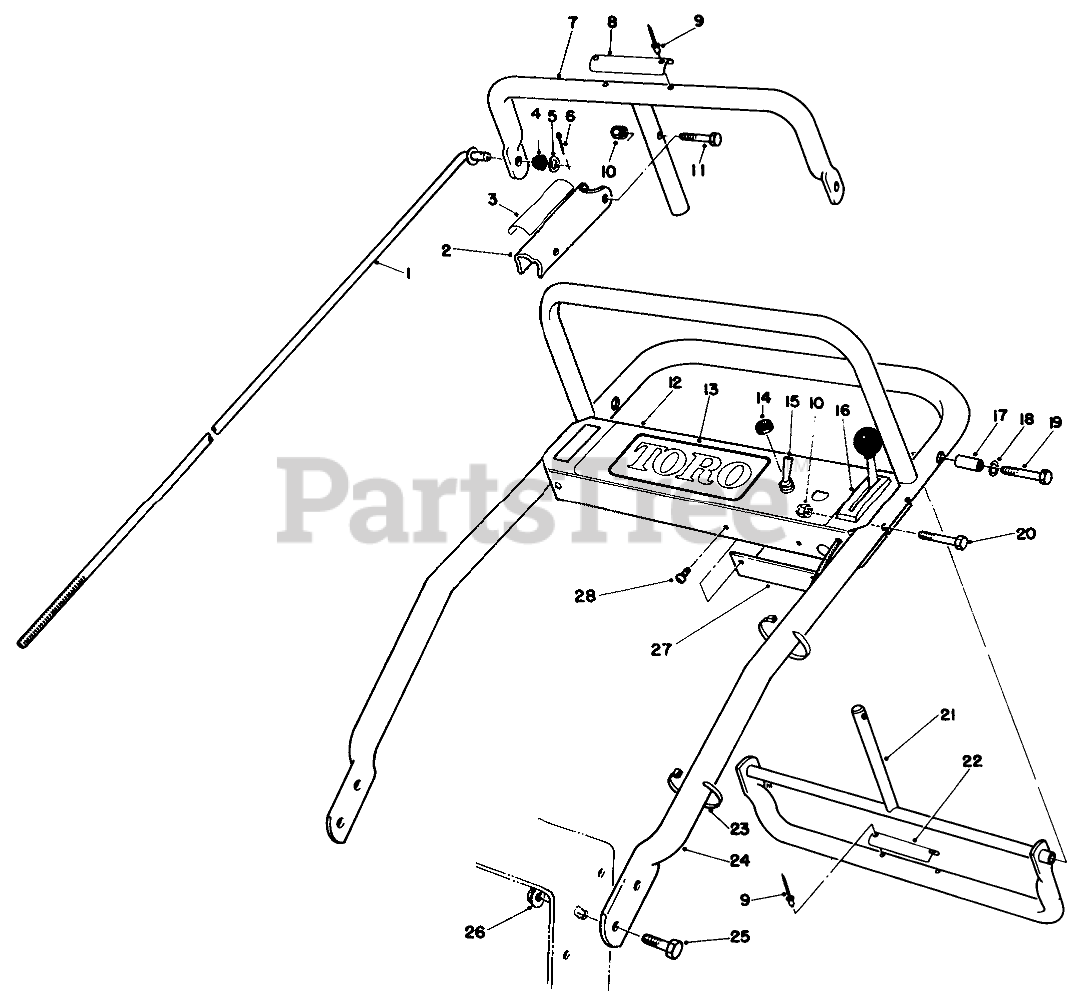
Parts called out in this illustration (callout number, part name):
1	CONTROL ROD B
2	Lever-Parking Brake
3	DECAL-LEVER, PARKING
4	GROMMET-RUBBER
5	WASHER-PLAIN
6	PIN-COTTER
7	Control Bar
8	DECAL-CONTROL BAR
9	RIVET-BLIND
10	NUT-LOCK, NI
11	SCREW-SHH
12	Panel-Control
13	PANEL DECAL
14	NUT
15	Switch
16	Control-Throttle
17	PIVOT-SPACER
18	WASHER-LOCK
19	SCREW-HH
20	SCREW-SHH
21	Control-Pivot
22	DECAL-REVERSE HANDLE
23	TIE-CABLE
24	Handle-Upper
25	SCREW-HHF
26	NUT-HF
27	PANEL-BOTTOM
28	SCREW-HWHTF
